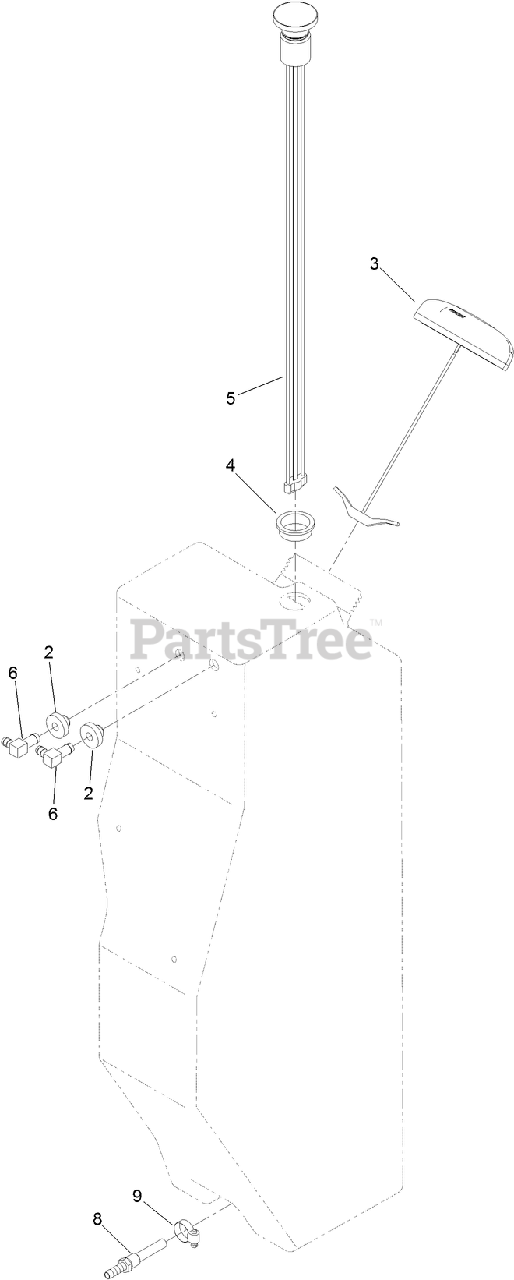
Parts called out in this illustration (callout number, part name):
2	BUSHING
3	CAP-FUEL
4	GROMMET
5	GAUGE-LEVEL, FUEL
6	FITTING-ELBOW, 90 DEG
8	FITTING-STRAINER
9	CLAMP-HOSE
